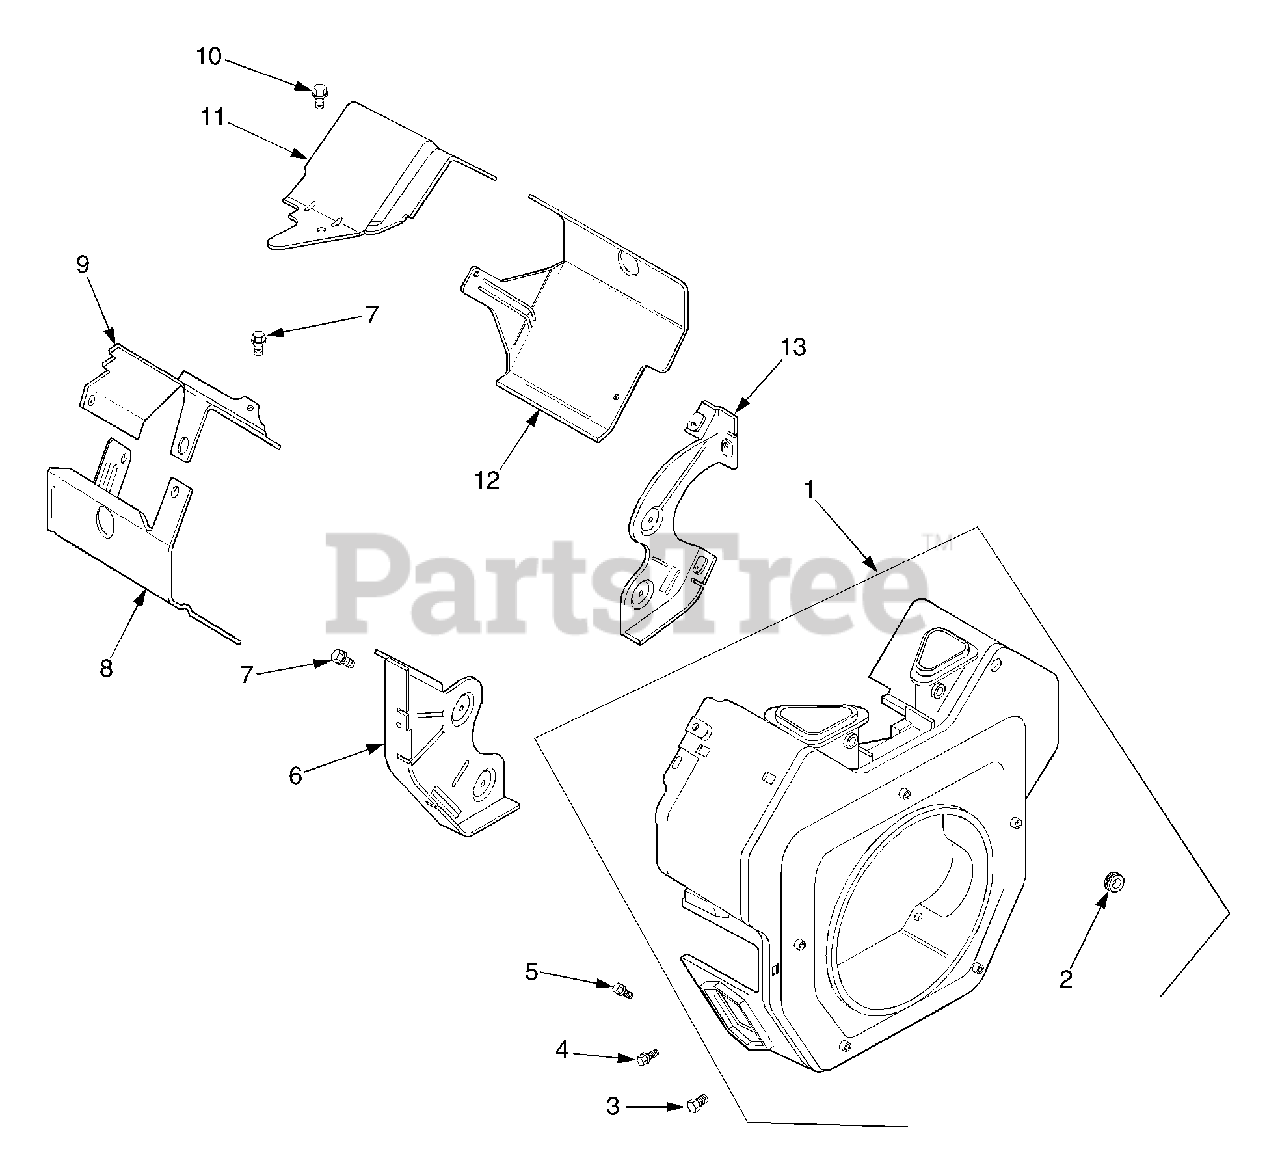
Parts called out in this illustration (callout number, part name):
1	Housing, Blower
3	Screw, Hex Flange M5 x 0.8 x 16
4	Screw, Hex Flange M5 x 0.8 x 16
5	Screw, Hex Flange M5 x 0.8 x 20
6	Plate, Backing #2 Side
7	Screw, Hex Flange M6 x 1.0 x 16
8	Baffle, Cyl. Barrel #2 Side
9	Baffle, Valley #2 Side
10	Screw, Hex Flange M5 x 0.8 x 10
11	Baffle, Valley #1 Side
12	Baffle, Cyl. Barrel #1 Side
13	Plate, Backing #1 Side
